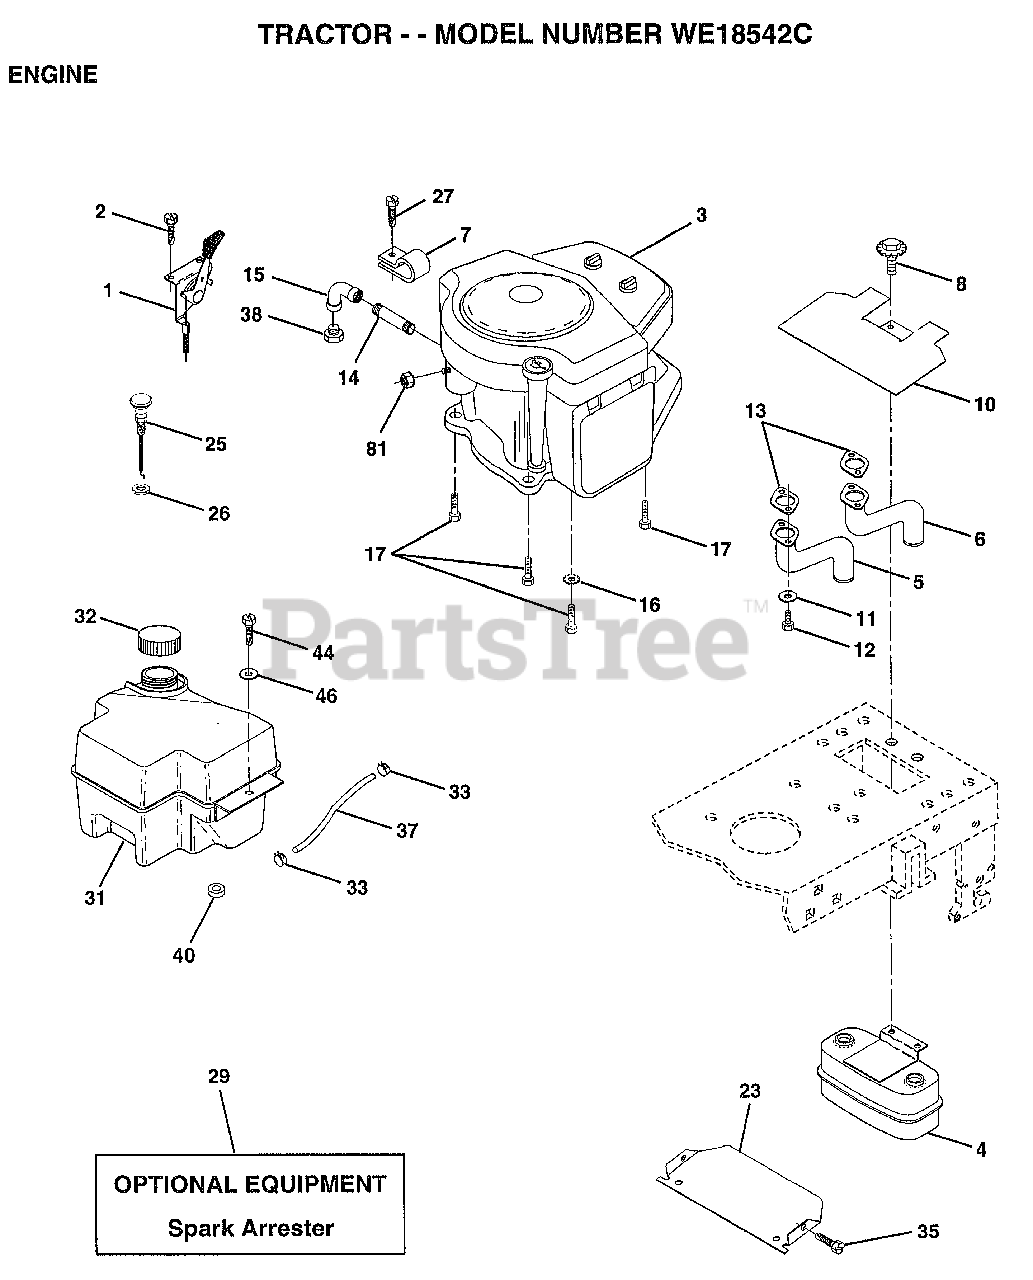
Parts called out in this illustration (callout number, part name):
1	CONTROL THRT 35.5
2	SCREW LT
4	MUFFLER.TW.LOTONE
5	EXHAUST.B&S.18.LH
6	EXHAUST.B&S.18.RH
7	CLAMP.TUBE.DBL.EN
8	BOLT.5/16-18.UNC
10	SHIELD.HEAT.
11	LOCKWASHER
13	GASKET MUFFLER
14	PIPE NIPPLE LT
15	ELBOW
16	LOCKWASHER
17	SCREW LT
23	SHIELD.BRN/DBR.GD
25	CONTROL.CHOKE.37
26	"NUT,KEPS 3/8-24IM"
27	"SCREW-TT,10-32 FL"
31	TANK.FUEL.FRONT.
32	CAP ASM FUEL
33	HOSE CLAMP
35	SCREW
37	LINE FUEL
44	SCREW HEX CRT
46	WASHER
81	NUT
